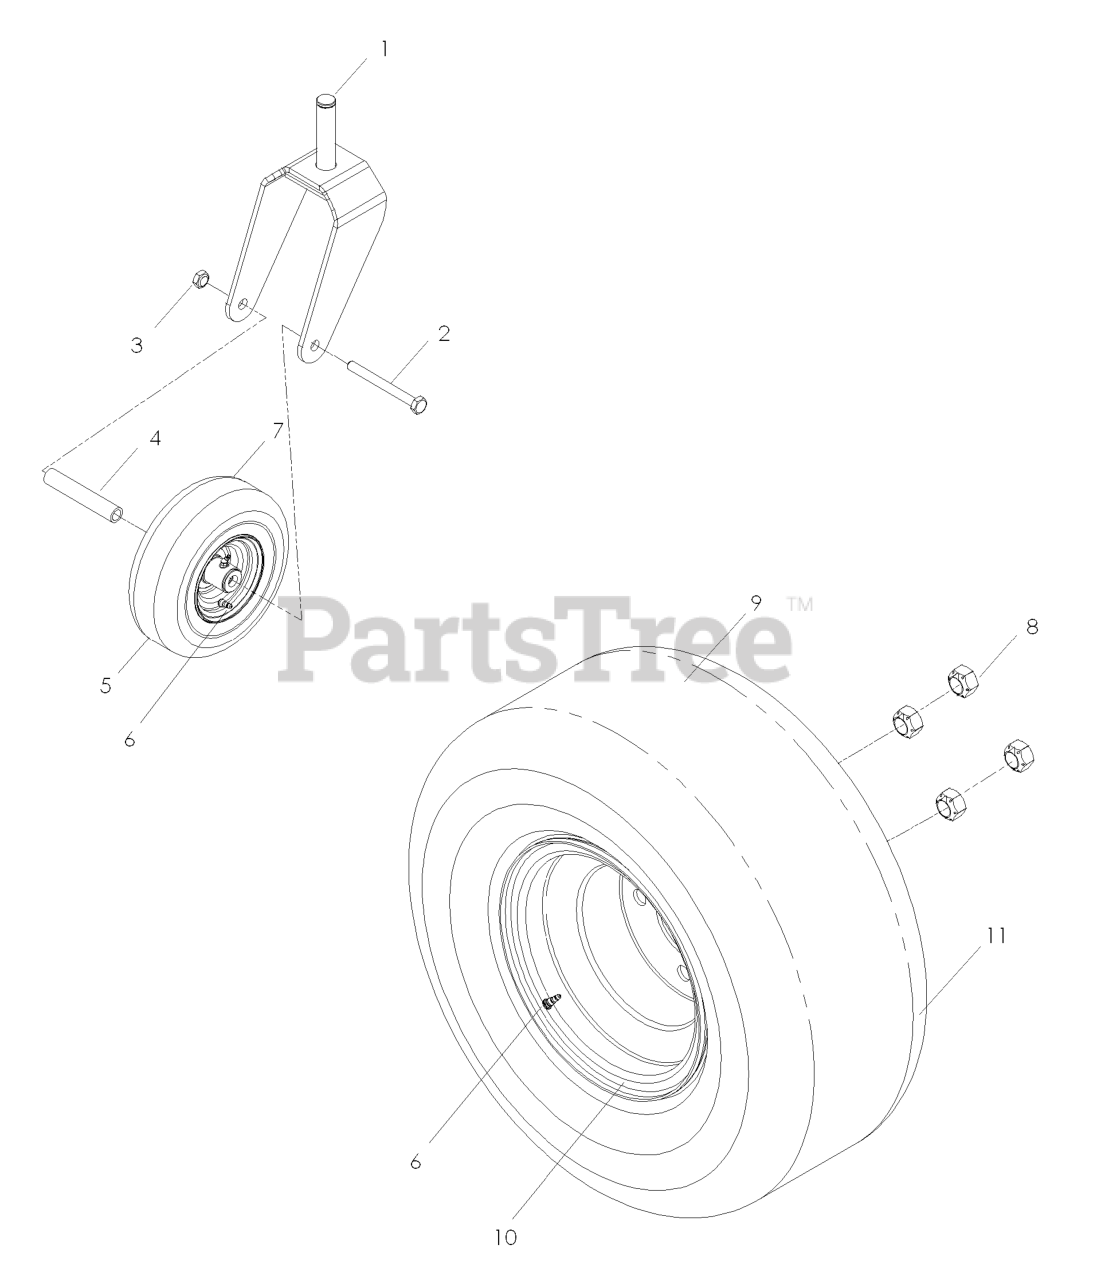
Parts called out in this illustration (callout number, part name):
1	CASTER WLDT
2	HCS 1/2C X 5 1/2
3	NUT 1/2-13 HEX NYLOC ZD
5	TIRE COMPLETE
6	VALVE STEM TR-412
7	TIRE - CASTER
8	LUG NUT 1/2F
9	TIRE/WHEEL.ASSEM.18X7.5-8.ZTR
9	TIRE ASM, 20X10-.8 NEG SILVER
9	WHEEL ASM.18X8.5-8.KENDA.
9	TIRE/WHEEL ASM 18X9.5-8
10	RIM.8X7.W/8".OFFSET.SILVER.ZTR
11	TIRE, 20 X 10-8
11	TIRE, 18 X 9.5 - 8
